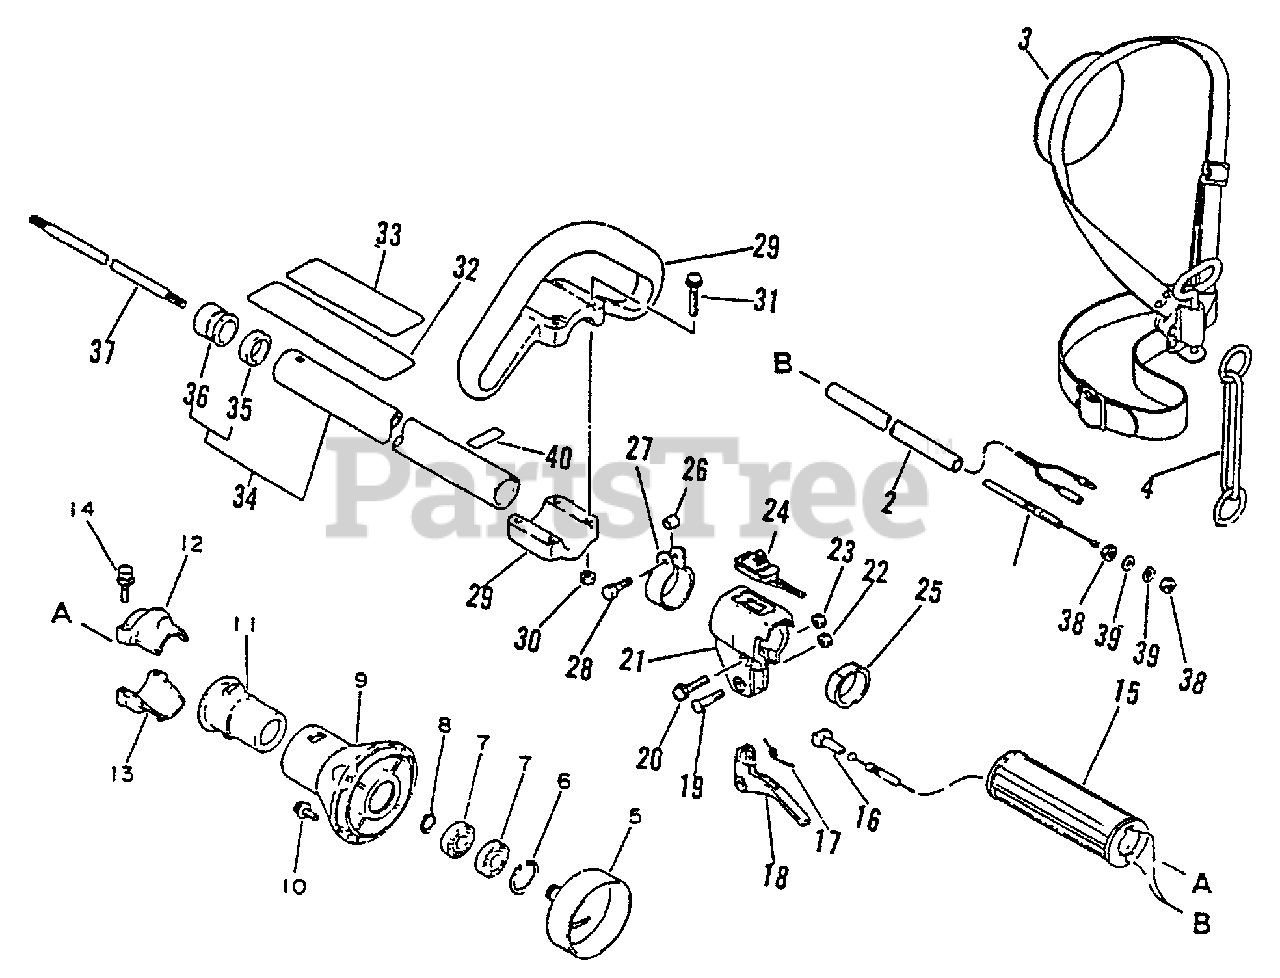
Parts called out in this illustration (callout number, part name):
1	CABLE, THROTTLE
3	SHOULDER STRAP ASSY
4	HOOK
5	DRUM, CLUTCH
6	RING, SNAP 28
7	BEARING, BALL 6001
8	RING, RETAINING - 12
9	CASE, CLUTCH
10	SCREW 5×16
12	HOLDER
13	HOLDER
14	BOLT - 5×25
15	GRIP
16	GUIDE, CABLE
17	SPRING, THROTTLE
18	TRIGGER, THROTTLE
20	SCREW 5×30
21	BRACKET, THROTTLE CONTROL
22	NUT, LOCK M5
23	NUT M5
24	SWITCH, ON-OFF
25	SPACER
26	SPACER, GUARD
28	BOLT 5×18
29	LOOP HANDLE ASSY
30	NUT M5
31	SCREW 5×35
32	LABEL - CAUTION
33	LABEL - CAUTION
34	MAIN PIPE ASSY 25×1500
37	DRIVESHAFT
39	WASHER 6.5×11.5×0.8
40	LABEL - ALIGNMENT
